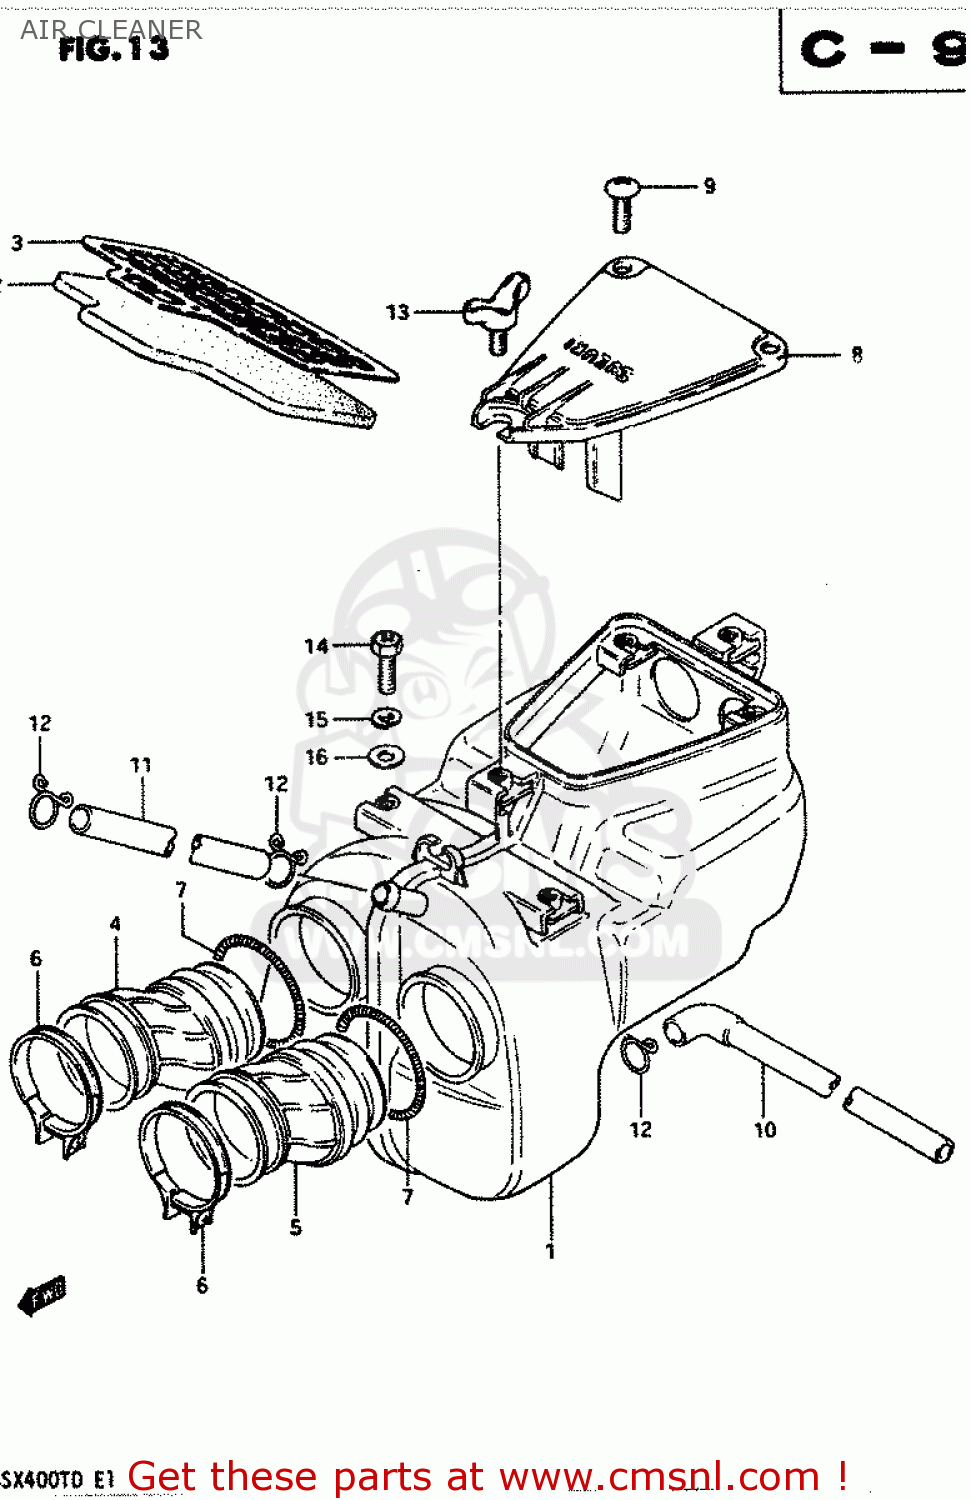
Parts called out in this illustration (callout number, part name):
1	CLEANER ASSEMBLY,AIR
2	FILTER
3	HOLDER,OUTER
4	TUBE,OUTLET,R
5	TUBE,OUTLET,L
6	CLAMP
7	CLAMP,CLEANER SIDE
8	CAP,AIR CLEANER
9	SCREW
10	DRAIN TUBE
11	TUBE,BREATHER
12	CLAMP
13	BOLT, WING
14	SCREW(6X12)
15	LOCK WASHER
16	WASHER
